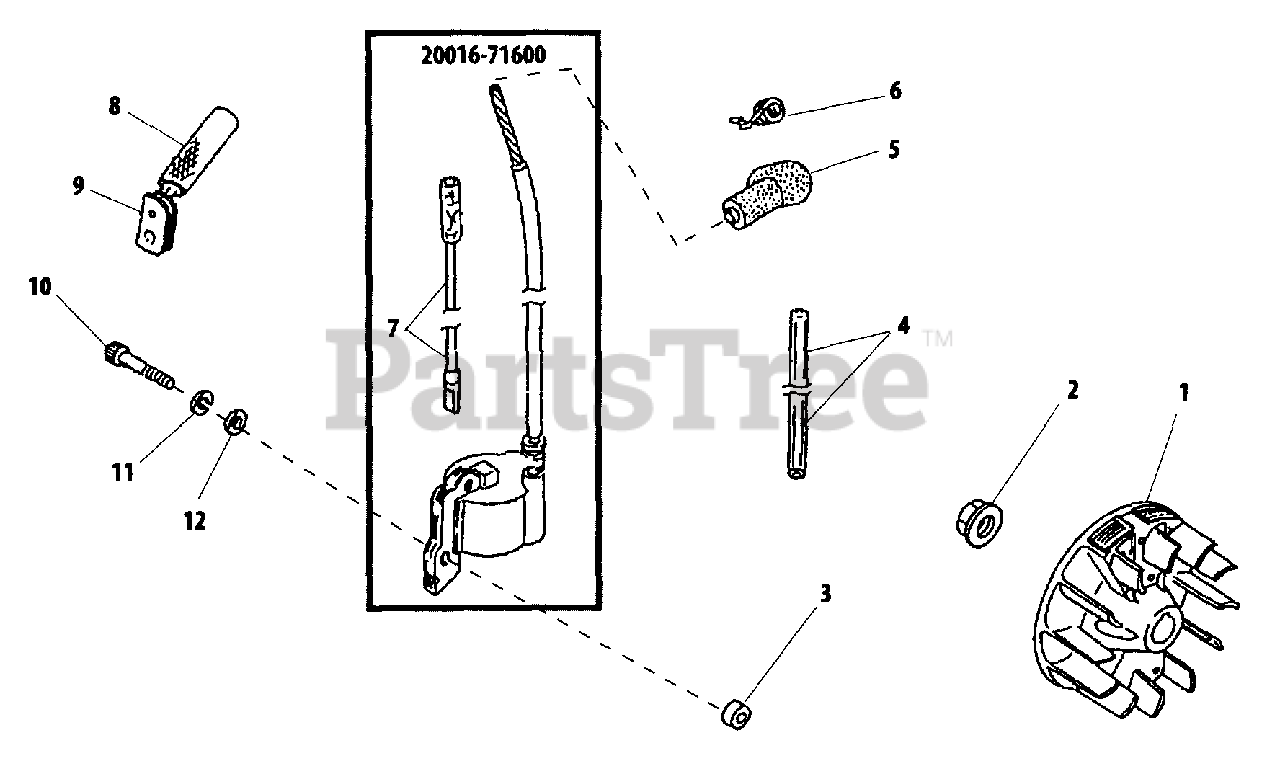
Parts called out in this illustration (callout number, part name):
1	FLYWHEEL
2	NUT M8
3	INSULATOR 4.2×11×6
4	TUBE, INSULATOR
5	CAP, SPARK PLUG
6	TERMINAL, SPARK PLUG
7	WIRE
8	TUBE, IGNITION COIL
9	GROMMET
10	BOLT
11	WASHER, SPRING 4 MM
12	WASHER 4 MM
20016-71600	IGNITION COIL ASSY
